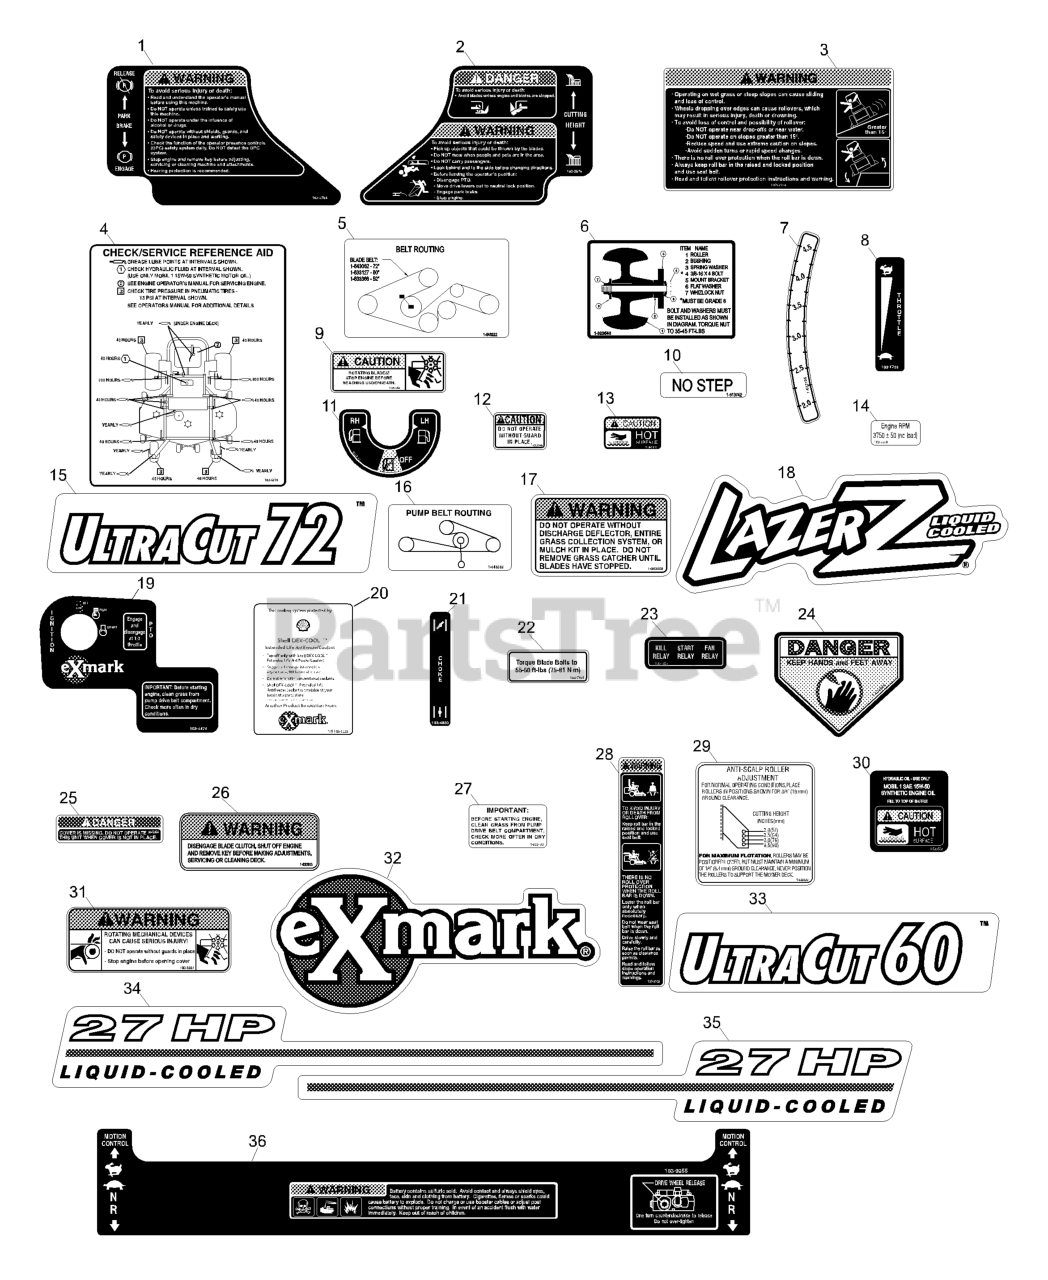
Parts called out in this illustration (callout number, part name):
1	DECAL,PARK BRAKE
2	DECAL,CUTTING HEIGHT
3	DECAL-WARNING
4	DECAL,CHECK SERVICE LZ
5	DECAL,BELT ROUTING
6	DECAL,ROLLER MOUNTING
7	DECAL-HEIGHT, DECK
8	DECAL,THROTTLE ONLY
9	DECAL-FAN, RADIATOR
10	DECAL,NO STEP
11	DECAL-VALVE, FUEL
12	DECAL-GUARD
13	DECAL-CAUTION
15	DECAL,ULTRACUT 72
16	DECAL-ROUTING, BELT
17	DECAL-WARNING, DISCHARGE
19	DECAL,IGNITION/PTO
20	DECAL,SHELL COOLANT
21	DECAL,CHOKE
23	DECAL-RELAY
24	DECAL-DANGER
25	DECAL-COVER, MISSING
26	DECAL,WARNING
27	DECAL-IMPORTANT
28	DECAL-WARNING, FOLDING RO
29	DECAL,ANTISCALP
31	DECAL-DEVICES, ROTATING
32	DECAL,EXMARK LOGO
33	DECAL,ULTRACUT 60
34	DECAL,HOOD 27LC LH
36	DECAL, TOP CONSOLE LZ
